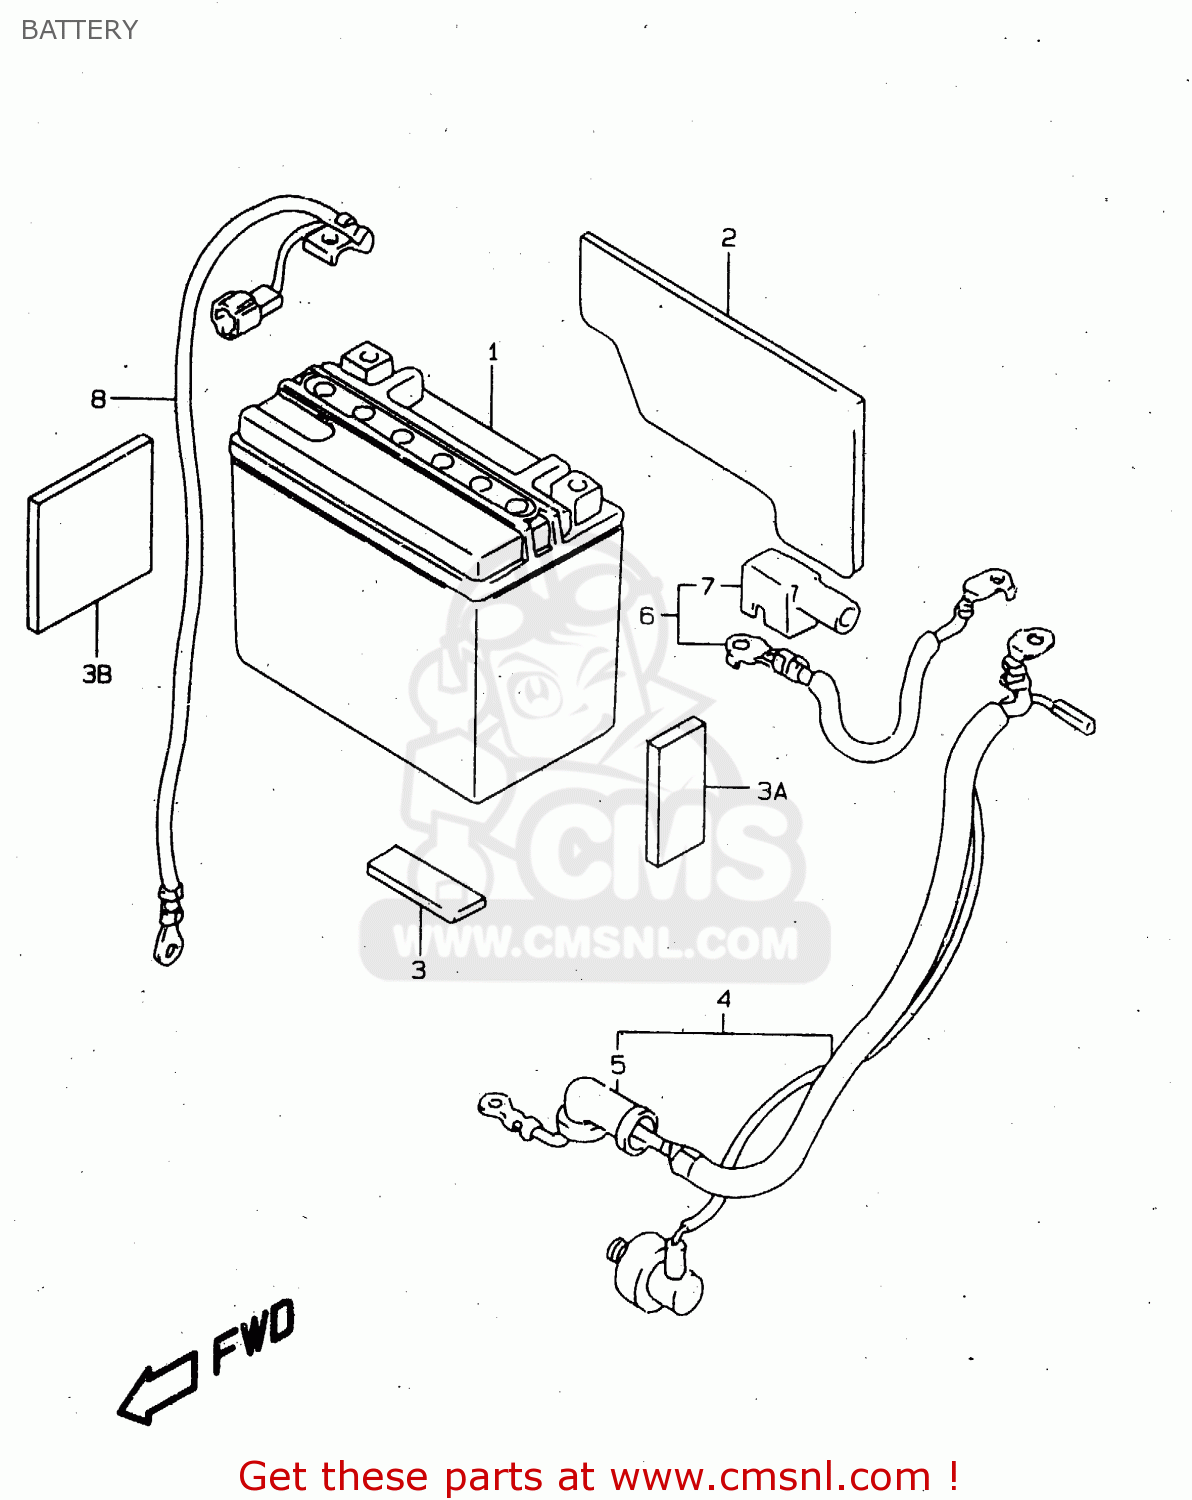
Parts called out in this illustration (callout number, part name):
1	BATTERY ASSEMBLY (12V) FTX
2	PROTECTOR(170X95X3.0)
3	PROTECTOR(20X50X8)
3A	CUSHION 20X45X6
3B	PROTECTOR(50X50X5)
4	WIRE,STARTER MOTOR LEAD
5	CAP,STARTER MOTOR LEAD
6	WIRE,BATTERY PLUS LEAD
7	CAP,BATTERY PLUS
8	WIRE,BATTERY MINUS
